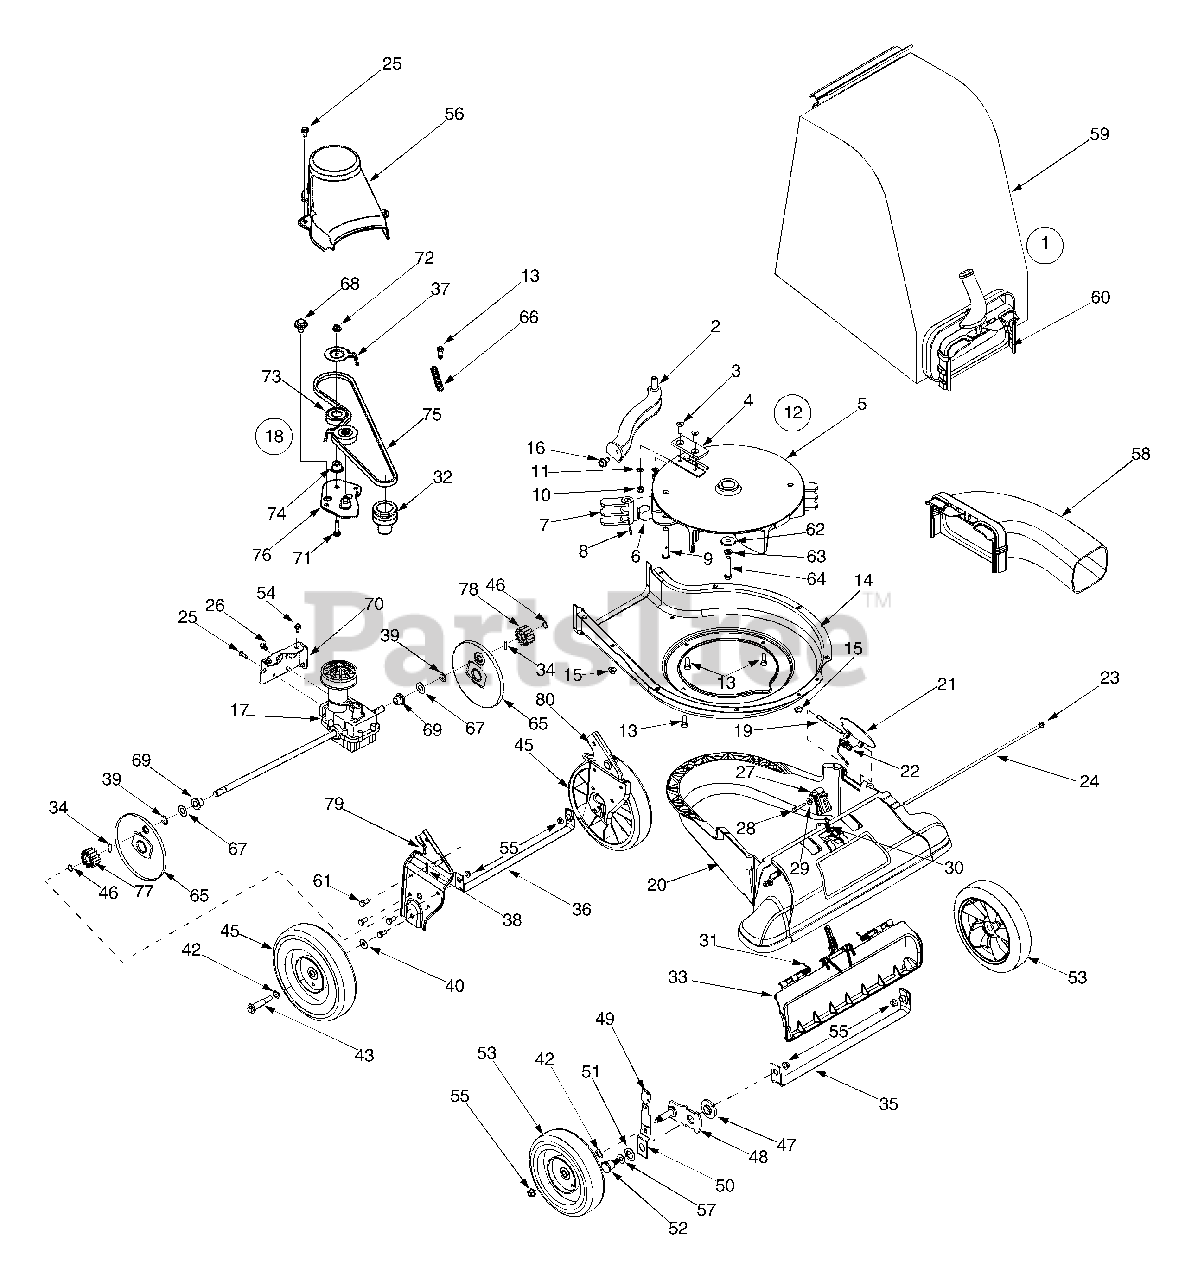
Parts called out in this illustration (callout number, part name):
1	Bag Assembly
3	Hex Screw 5/16-24 x 1.0
4	Chipper Blade
8	Spiral Pin
9	Clevis Pin
10	Lock Nut, 5/16-24
11	Lock Washer, 5/16
12	Impeller Assembly
13	Shoulder Screw, #12-24 x.30 x.46
15	Flange Lock Nut 5/16-18
16	Screw, 5/16-18 x.500
17	Transmission Assembly
18	Idler Assembly
20	Nozzle
21	Base Adapter Door
22	Torsion Spring
23	PUSH NUT
24	Pivot Rod
25	Screw, 1/4-20 x.500
26	Screw, #12-16 x.750
27	Nozzle Door Lever
28	Hex Screw, #8-18 x 1.25
29	Shoulder Spacer
30	Extension Spring
31	Nozzle Door Torsion Spring
32	Impeller Hub
33	Nozzle Door
34	Dowel Pin
37	Belt Keeper
38	Cotter Pin
39	E - Ring
40	Flat Washer,.385 x 1.00 x.135
42	Wave Washer.531 ID x.781 OD
43	Shoulder Screw 3/8-16
45	Wheel 8 x 2.125
46	Snap Ring
47	Height Adjustment Bearing
48	Pivot Arm Assembly
49	Height Adjustment Knob
50	Spring Lever
51	Bell Washer.760 ID x.25 OD
52	Shoulder Screw,.750 x.500
53	Wheel 8 x 2
54	Screw, 1/4-20 x.625
55	Flange Lock Nut, 3/8-16
56	Belt Cover
57	Thrust Washer.375 ID x.70 OD
58	Blower Chute
60	Chute Assembly
61	Hex Index Screw, 5/16-12 x.750
62	Flat Washer.375 ID x 1.25 OD
63	Lock Washer 3/8
64	Hex Cap Screw 3/8-24 x 2.75
65	Wheel Cover
66	Extension Spring,.375 x 2.95
67	Flat Washer,.508ID x1.00OD x.020
68	Shoulder Screw,.560 x.165
69	Drive Axle Bushing
71	SCREW 1/4-20 X1.00 GR5
72	Flange Lock Nut, 1/4-20
73	Ball Bearing
74	Flange Spacer,.260 x.659 x.517
75	Belt, 3/8 x 32.5
77	Spur Gear - RH
78	Spur Gear - LH
